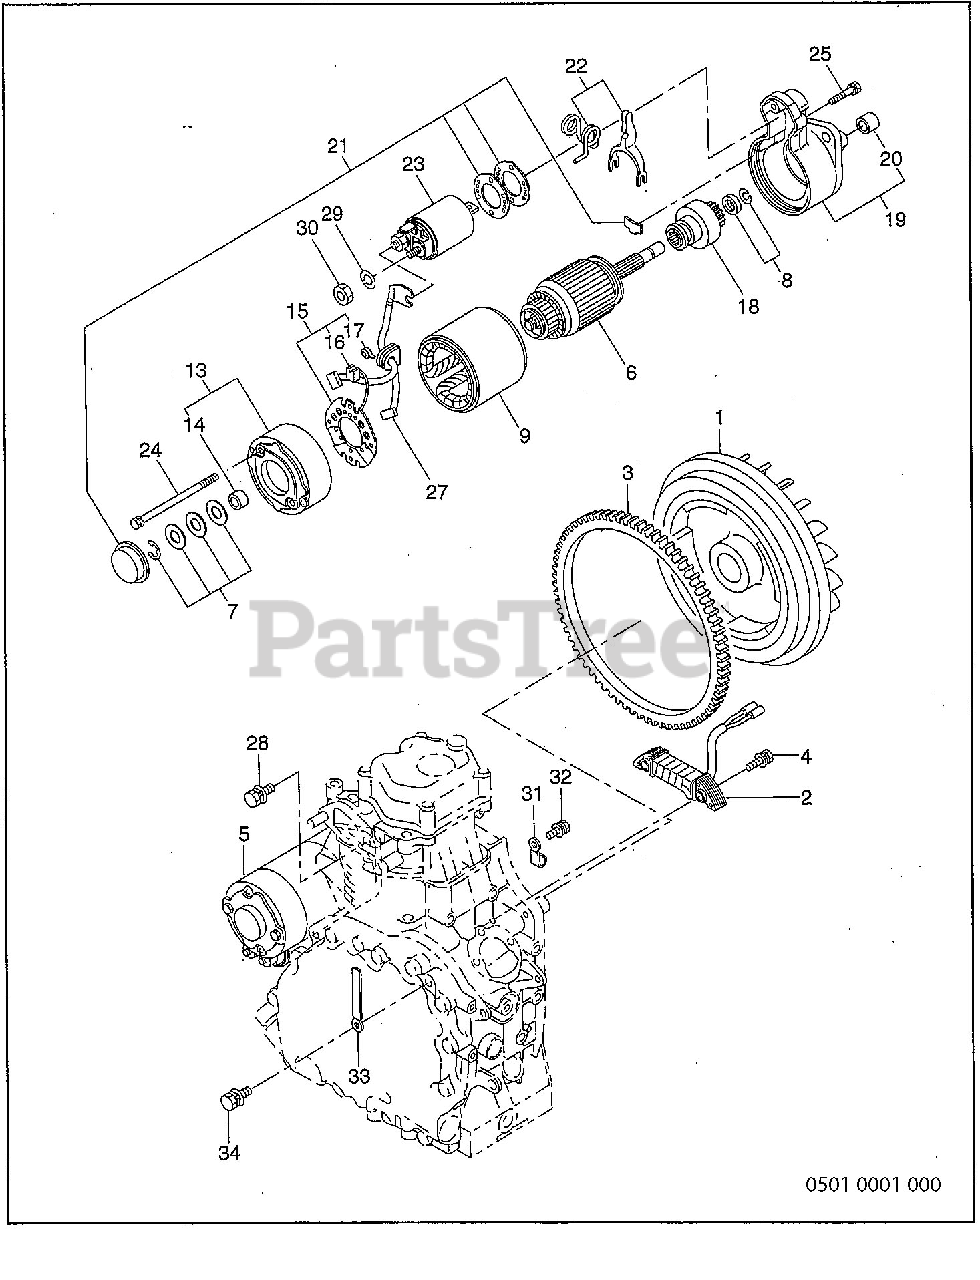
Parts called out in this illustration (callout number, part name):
1	!FLYWHEEL ASSY
2	EXCITER COIL ASSY
4	SCREW and WASHER ASSY
5	STARTING MOTOR ASSY
7	THRUST WASHER KIT
8	PINION STOPPER SET
13	REAR COVER ASSY
15	BRUSH HOLDER ASSY
19	GEAR CASE ASSY
20	STARTER METAL
21	DUST COVER KIT
22	SHIFT LEVER KIT
23	MAGNETIC SWITCH ASSY
28	BOLT and WASHER ASSY
31	CLAMP
32	SCREW and WASHER ASSY
34	BOLT and WASHER ASSY
